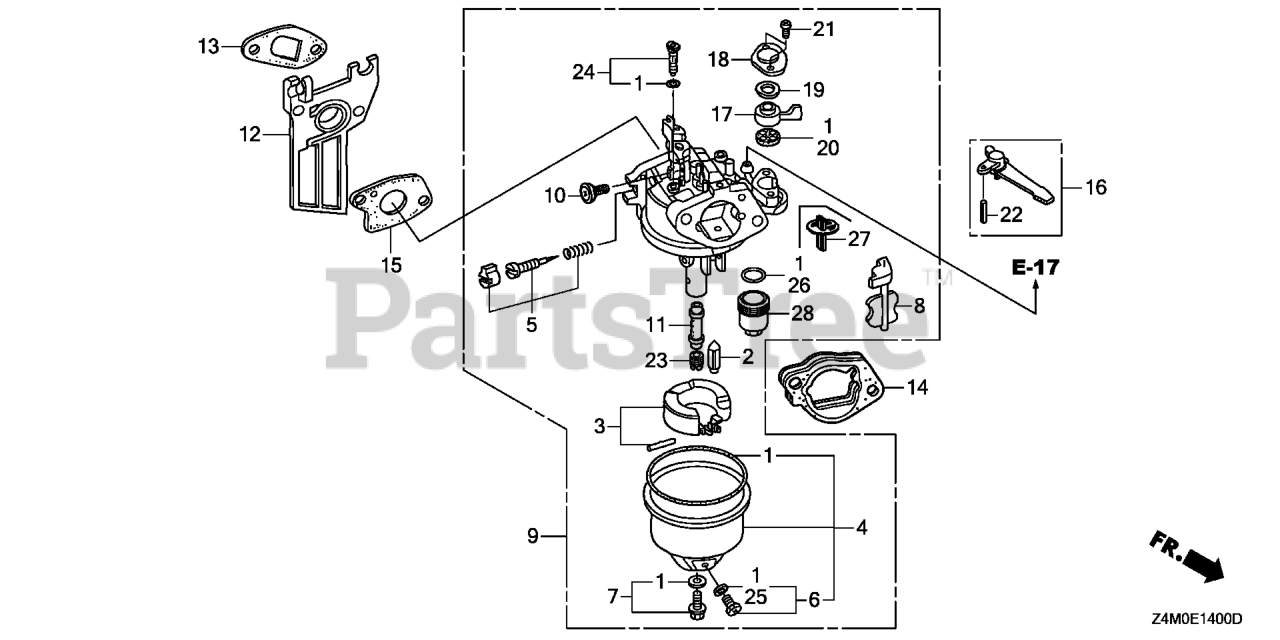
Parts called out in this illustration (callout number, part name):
1	GASKET SET
2	VALVE SET, FLOAT (CARBURETOR NO.) (SEAT NOT INCLUDED)
3	FLOAT SET
4	CHAMBER SET, FLOAT
5	SCREW SET
6	SCREW SET, DRAIN
7	SCREW SET (CARBURETOR NO.)
8	CHOKE SET
9	CARBURETOR ASSY. (BE99N A)
10	SCREW, THROTTLE STOP
11	NOZZLE, MAIN (CARBURETOR NO.)
12	INSULATOR, CARBURETOR
13	GASKET, INSULATOR
14	SPACER, CARBURETOR
15	GASKET, CARBURETOR
16	LEVER, CHOKE (STD)
17	LEVER, VALVE
18	PLATE, LEVER SETTING (CARBURETOR NO.)
19	SPRING, PETCOCK LEVER (CARBURETOR NO.)
20	GASKET, VALVE
21	SCREW, PAN (3X6)
22	PIN, SPRING (2X12)
23	JET, MAIN (#65)
23	JET, MAIN (#68)
23	JET, MAIN (#70)
24	JET SET, PILOT (#38)
25	WASHER, PLAIN (6.2X10.7 DRAIN) (CARBURETOR NO.)
26	GASKET, FUEL STRAINER CUP
27	FILTER, CUP (CARBURETOR NO.)
28	CUP, FUEL STRAINER
